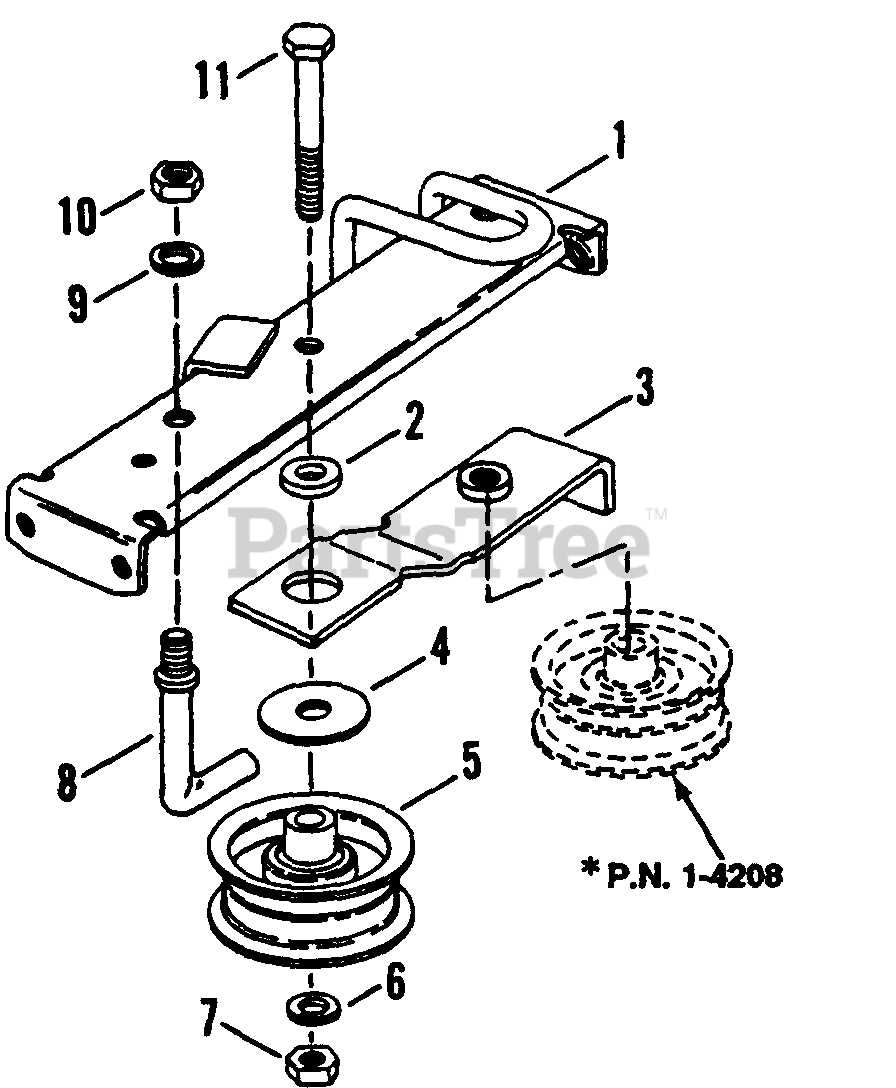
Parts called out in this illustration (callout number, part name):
1	(NLA) BRACKET, Idler
2	SPACER, .632 OD x .328 ID x .21 Long
3	ARM, Idler
4	WASHER, 11/32 Flat
5	IDLER, 2.5" Flat
6	WASHER, 5/16 Split Lock
7	NUT, 5/16-24 Hex Head
8	GUIDE, Belt
9	WASHER, 3/8 Split Lock
10	NUT, 3/8-24 Hex Head
11	SCREW, 5/16-24 x 2" Hex Head Cap, Grade 5
